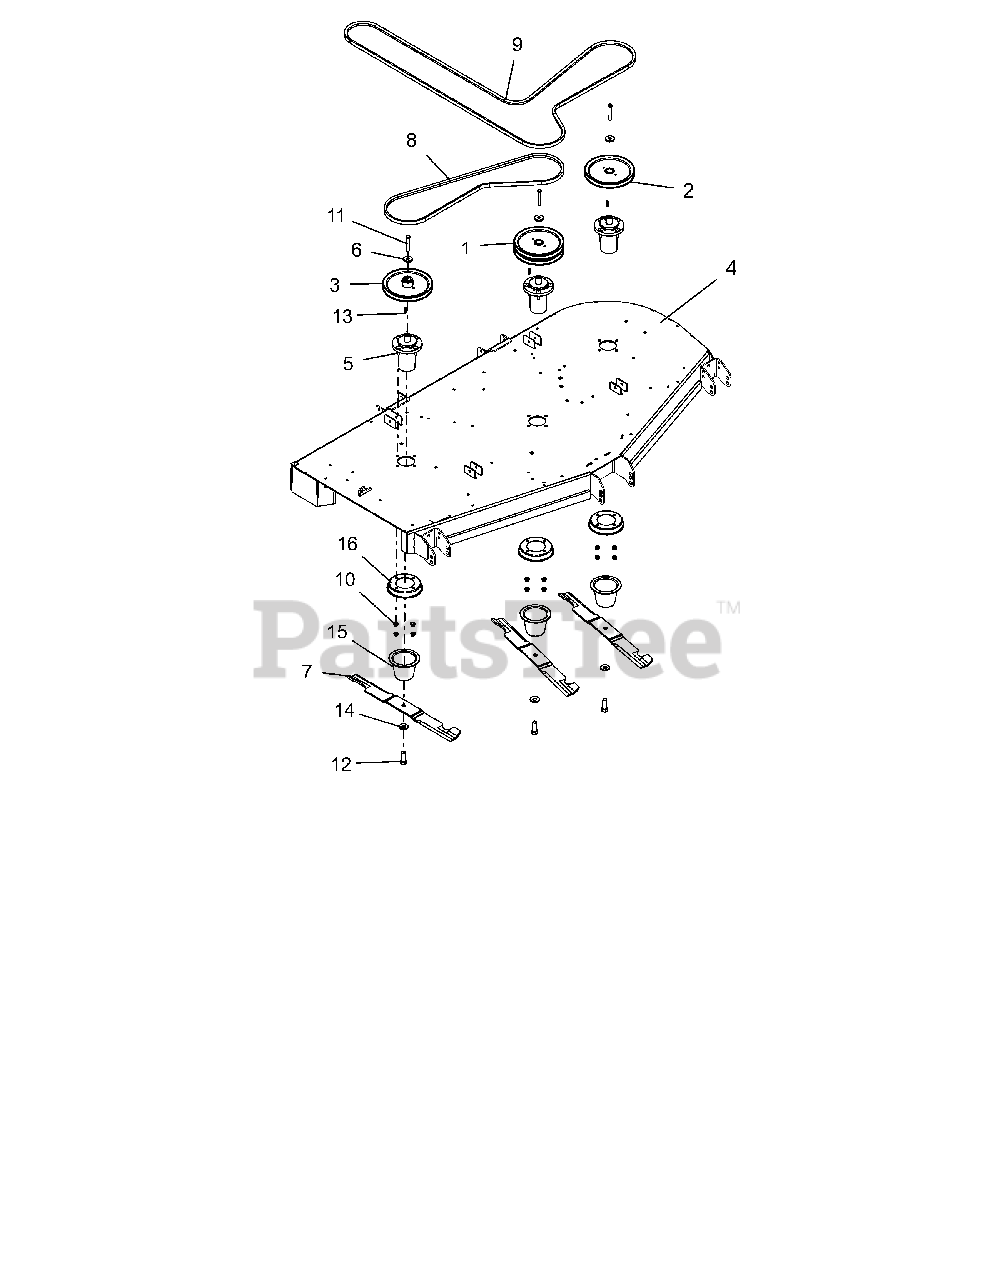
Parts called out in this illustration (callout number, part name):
1	SHEAVE-DOUBLE 1.00"IDX8.25"OD
2	SHEAVE-SINGLE 1.00"IDX8.25"OD
3	SHV-SINGLE 1.00"ID X 8.25"OD
4	72"SIDE DISCH DECK WMT W/SAFE
5	ASM, MAINT FREE ALUM SPINDLE
6	RETAINER, SHEAVE
7	BLADE, 72"
8	V-BELT, B-COGGED
9	V-BELT, HB WRAPPED
10	NUT-LK-CTR-FLG .38-16 YWZC
11	BLT-HEX .38-16X2.75 GR8 YWZC
12	BLT-HEX .62-18X1.75 GR8 YWZC
13	KEY, SQ .25X.25X1.00 RC 40-50
14	WSHR-BLVL .669X1.535X.138
15	GUARD, SPINDLE LOWER
16	GUARD, SPINDLE TOP
